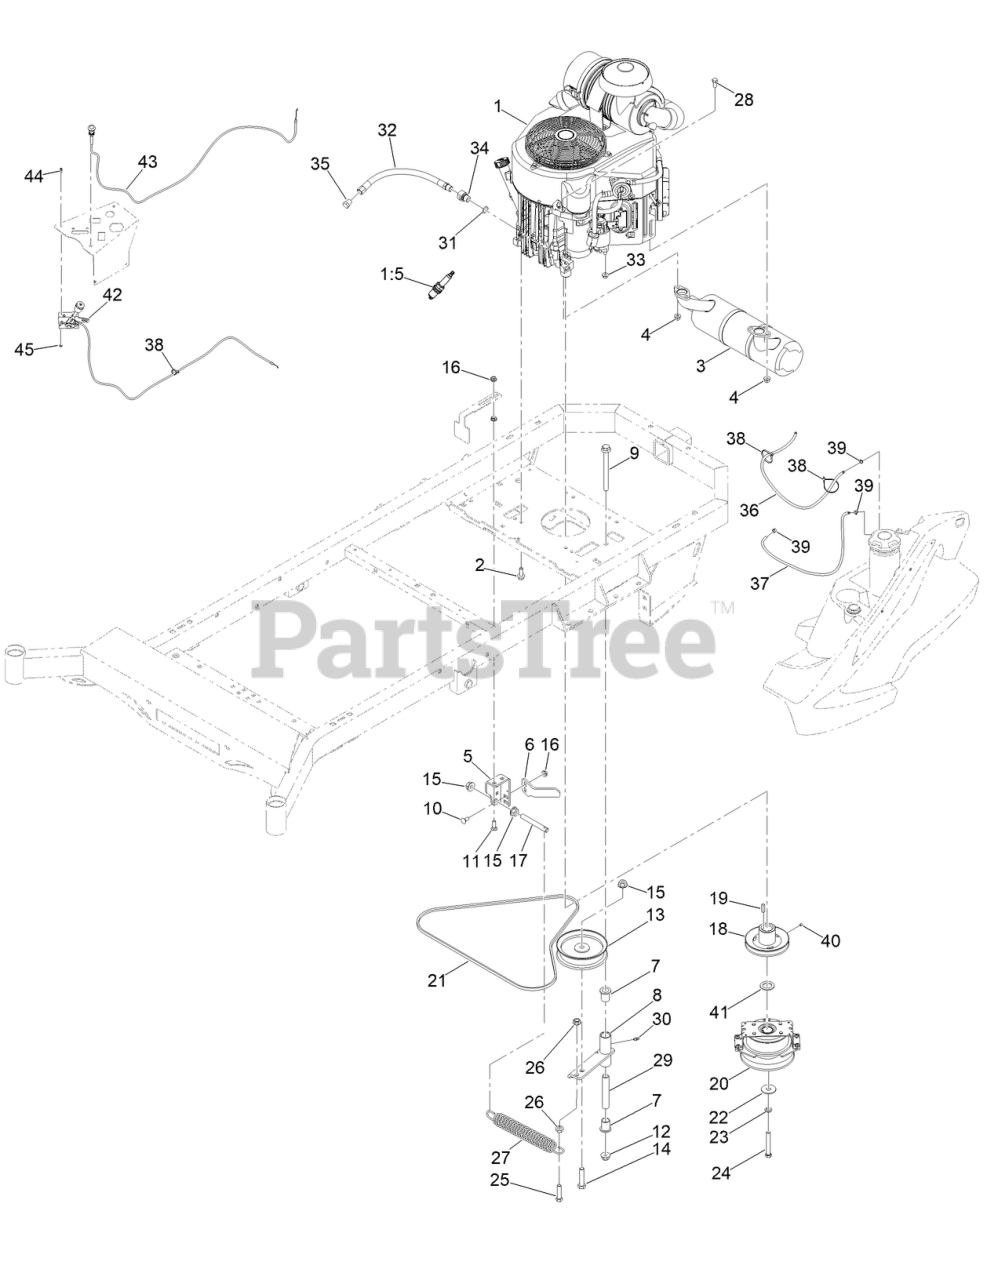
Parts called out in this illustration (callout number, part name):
1	ENGINE-KAWASAKI, FX730V
1:1	FILTER-OIL
1:2	Filter-Fuel
1:3	ELEMENT-FILTER, AIR (INNER)
1:4	ELEMENT-FILTER, AIR (OUTER)
1:5	SPARK PLUG
2	3/8-16 X 1-1/8 IND HWH W/SERR TRI LOB ZY
3	2019 EXHAUST SYST FOR KAWI FR FS AND FT
4	NUT-HF
5	MWR PUMP IDLER TENSIONING BRKT BLACK
6	2021 TTQ MOWER OGURA CLUTCH BRACKET
7	3/4IN ID X15/16IN OD X 1-1/8IN FLNG BUSH
8	MWR PUMP IDLER ASSY BLACK
9	1/2-13 X 5-1/2 HEX FLANGE BOLT GR 8 ZY
10	BOLT-CARR
11	5/16-18 X 1-1/4 CARRIAGE BOLT ZC/YEL
12	NUT-LOCK
13	5-3/4IN IDLER PULLEY 7/16IN SPACER ASSY
14	SCREW-HH
15	NUT-HHF
17	MWR PUMP IDLER SPRING TENSIONER
18	MWR HYDRAULIC PUMP DRIVE PULLEYA BELT
20	MWR TTQ OGURA CLUTCH
21	MWR PUMP BELT RT A X 68.25IN EFF LNGTH
22	1/2IN X 1-5/8 BELLEVILLE CUP WASHER YZ
23	WASHER-LOCK
24	TTQ CLUTCH BOLT
26	NUT-HF
27	MWR DECK SPRING
28	M8-1.25 X 20MM HEX FLANGE BOLT ZINC 10.9
29	MWR INNER IDLER SPACER
30	1/4IN DRIVE TYPE GREASE FITTING YZ
31	RING-O,15.8X2.4
32	HOSE-DRAIN, OIL
33	NUT-HF
34	3/8" FNPT to M20x2.5 adapter 59071-7023
35	3/8 MNPT OIL PLUG
36	MWR FUEL TANK BLACK 3/16IN VENT TUBE 1FT
36	MWR FUEL TANK BLK 3/16 VENT TUBE
37	1/4IN SAE J30R7 BULK HOSE 1FT
38	TIE-CABLE
39	1/2IN (#8) HOSE CLAMP
40	5/16-18 X 3/8 SOCKET SET SCREW
41	WASHER-THRUST
42	MWR THROTTLE CABLE ASSY W / HANDLE
43	MWR CHOKE CABLE ASSM
44	10-24 X 1/2 SOCKET C/S 18-8 SS
45	NUT-LOCK
